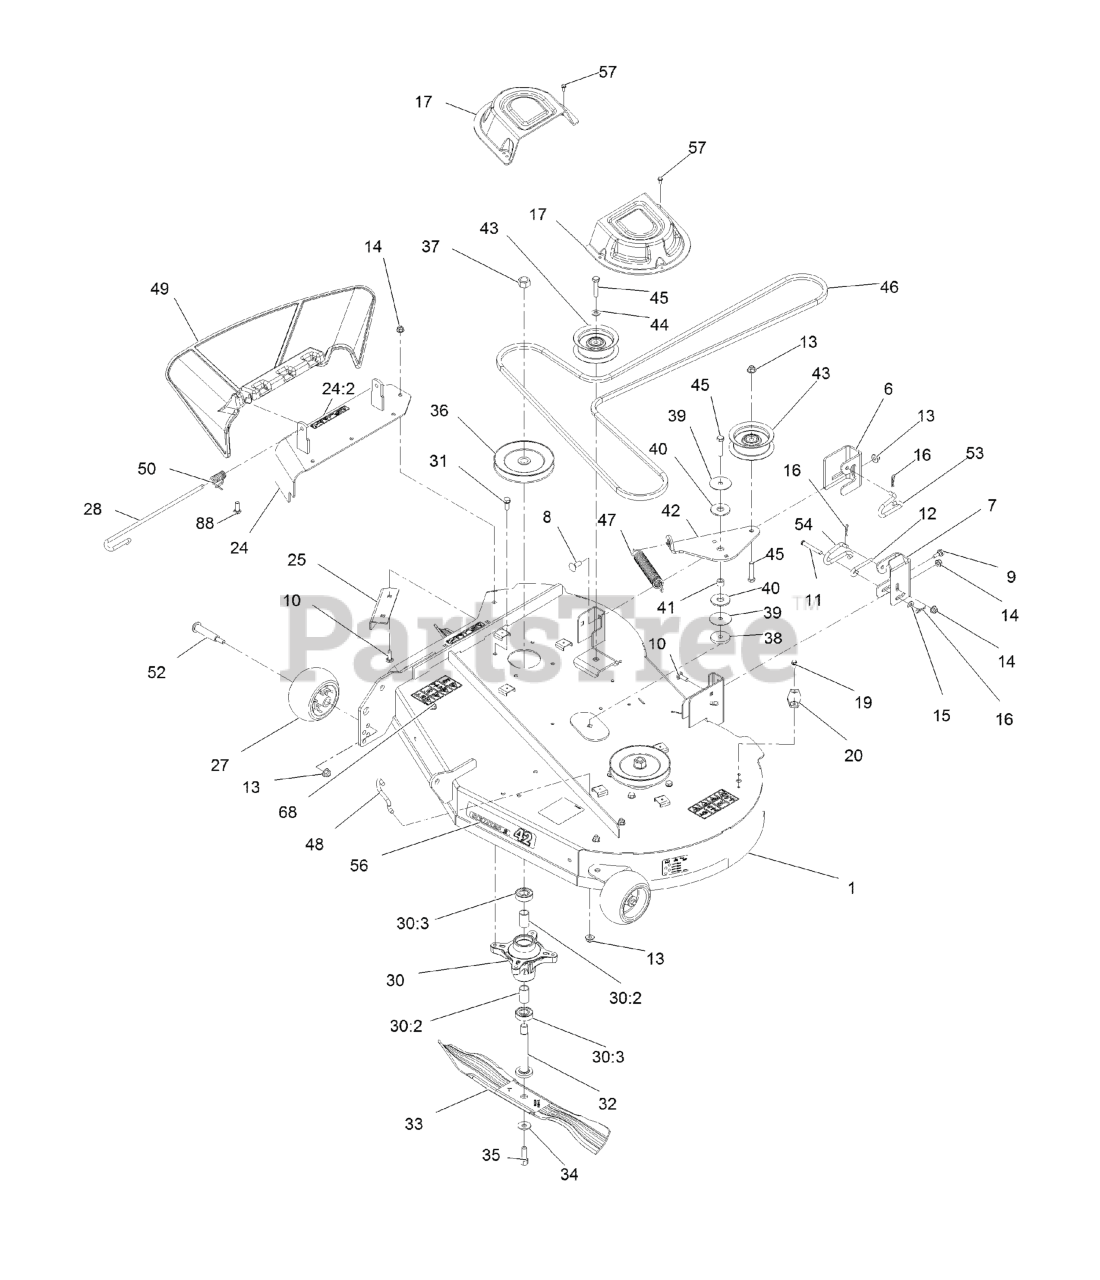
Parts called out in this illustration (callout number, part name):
1	DECK-42 W/DECALS
6	BRACKET-HANGER, RH
7	BRACKET-HANGER, LH
8	BOLT-CARR
9	SCREW-SHOULDER,HWH
10	SCREW-CARR
11	PIN-CLEVIS
12	ROD-LEVEL, DECK
13	NUT-HF, NI
14	NUT-HF, NI
15	WASHER-PLAIN
16	PIN-COTTER
17	COVER-BELT
19	SCREW-HWH
20	COVER-WASHOUT PORT
24	COVER ASM W/DECAL
24:2	DECAL-DANGER
25	BAFFLE-CUTOFF
27	ROLLER-SCALP, ANTI
28	PIN-CHUTE
30	SPINDLE ASM
30:3	BEARING-BALL
31	SCREW-TAPTITE
32	SHAFT-SPINDLE
33	BLADE-HIGH LIFT
34	WASHER-BELLEVILLE
35	SCREW-HH
36	PULLEY
37	NUT-HEX
38	WASHER-PLAIN
40	WASHER-FRICTION, COMPOSIT
42	ARM-IDLER
43	PULLEY-IDLER, FLAT
44	WASHER-FLAT
45	SCREW-HH
46	V-BELT
47	SPRING-EXTENSION
48	HOOK-RETURN, SPRING
49	DEFLECTOR-DISCHARGE
50	SPRING-TORSION
52	BOLT-SHOULDER
53	LINK-RETENTION, DECK (RH)
54	LINK-RETENTION, DECK (LH)
56	Decal-Series 2 - 42
57	SCREW-TAPTITE
68	SCREW-HH
88	SCREW-CARR
